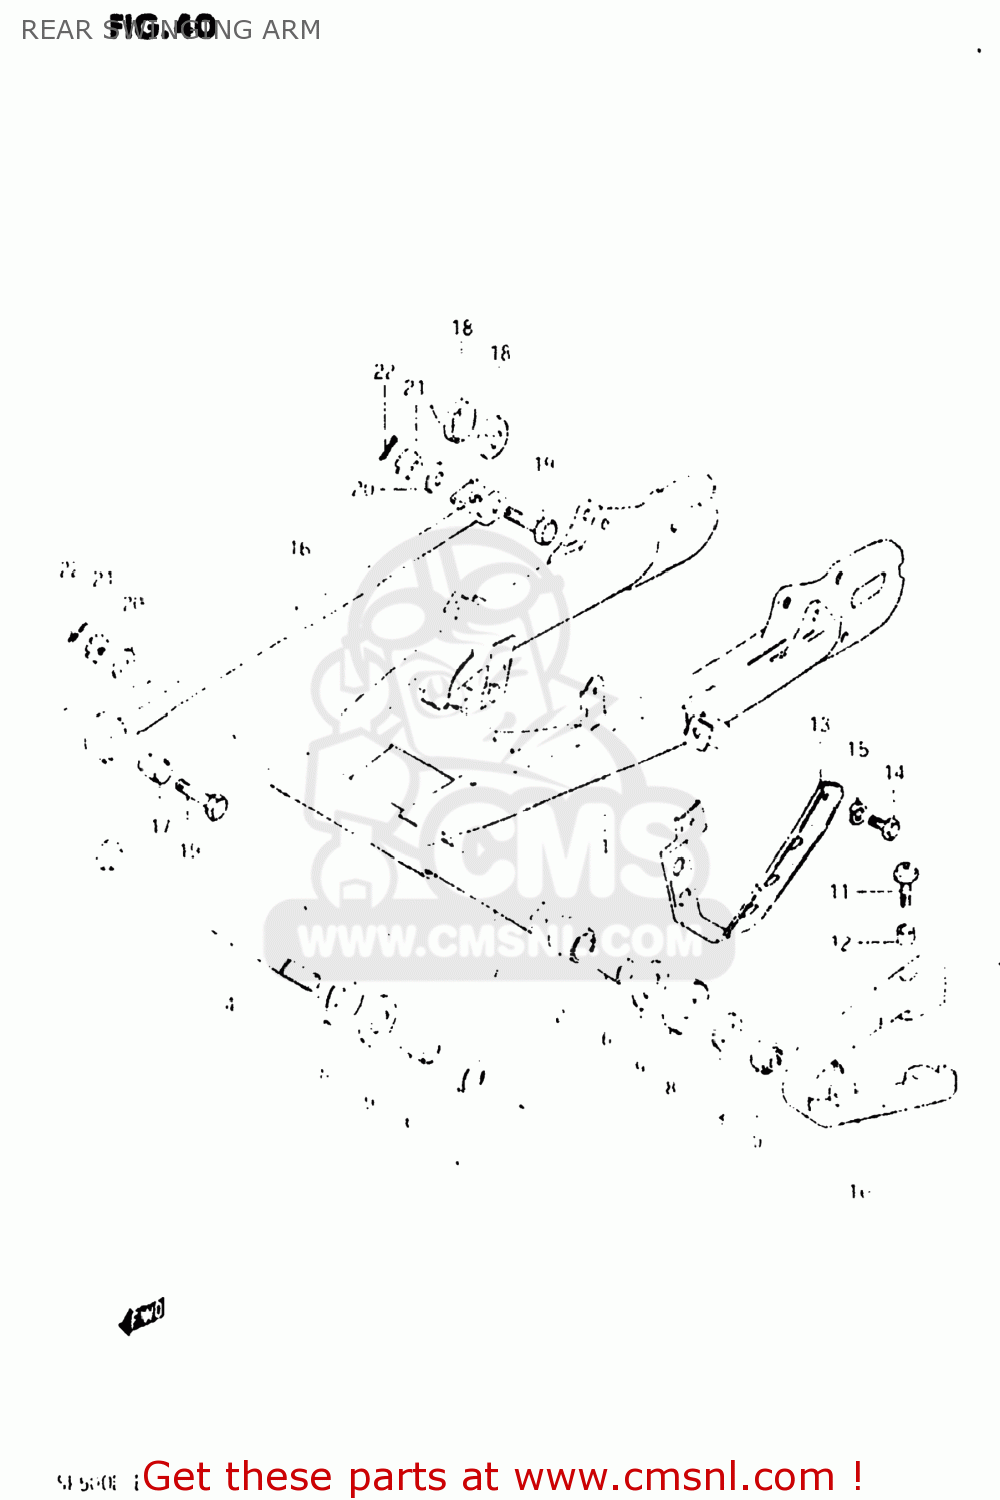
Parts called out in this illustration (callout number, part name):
1	ARM,REAR SWING
2	BEARING(22X29X20)
3	WASHER
4	SHAFT,REAR SWING ARM
5	NUT 16MM
6	SPACER,RR SWGARM PIVOT
7	SPACER (16.2X21.7X142)
8	COVER,RR SWGARM DUST SEAL
9	WASHER
10	BUFFER,CHAIN TOUCH DEFLECTOR
11	SCREW,CHAIN TOUCH DEFEND
12	SPACER (5.5X8X4)
13	GUIDE,CHAIN
14	BOLT 8X12
15	LOCK WASHER
16	LINK,REAR TORQUE
17	BUSH
18	19
19	BOLT 8X29.5
20	WASHER
21	NUT 8MM
22	PIN 20X20
